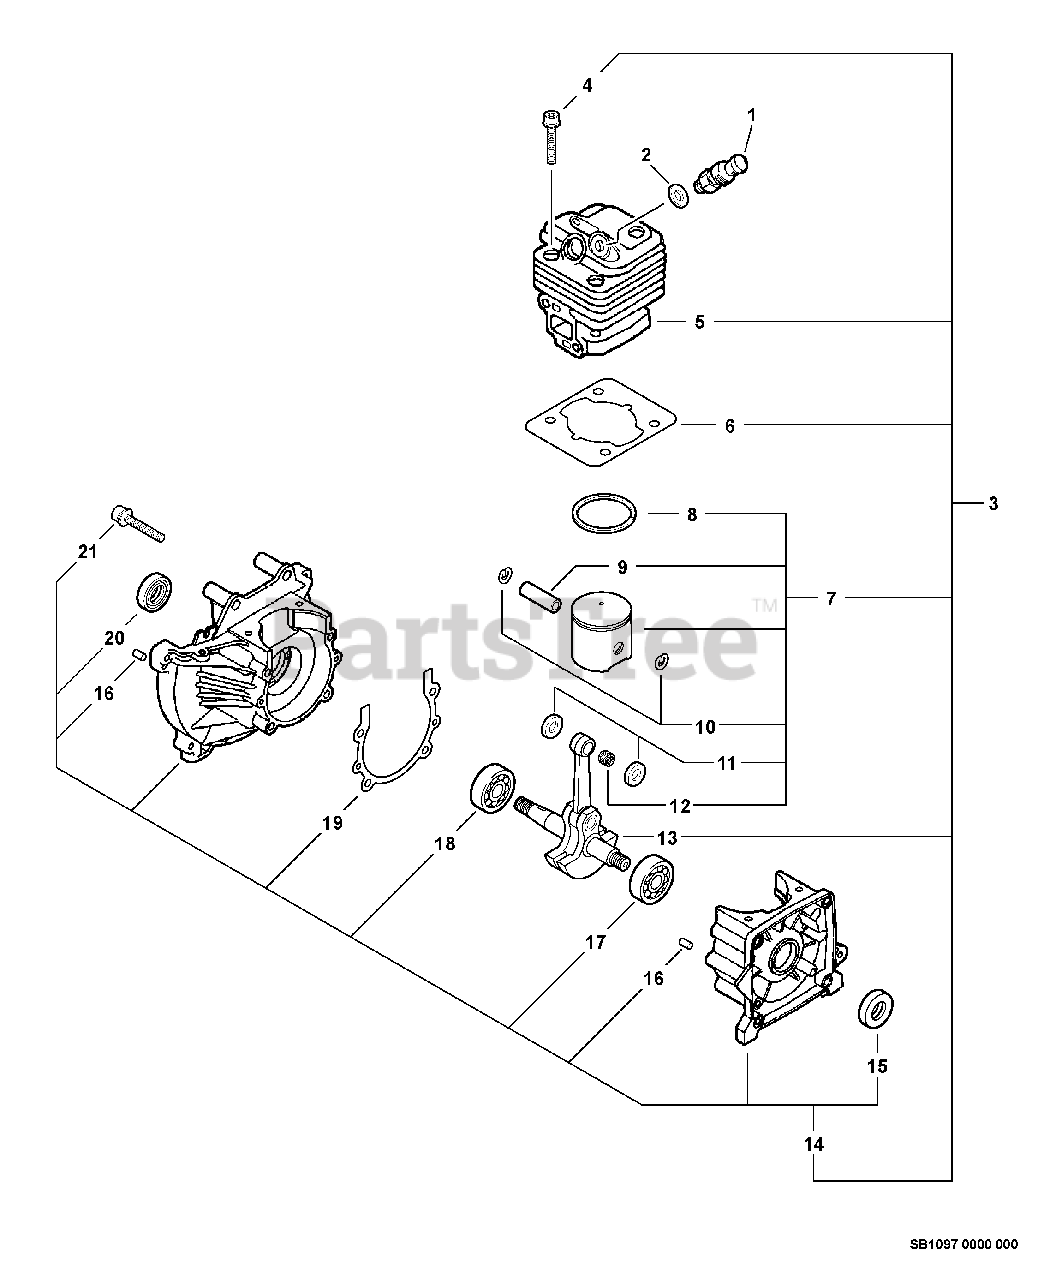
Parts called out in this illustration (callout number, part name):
1	DECOMPRESSION ASSY
2	WASHER
3	SHORT BLOCK -- SB1097
4	SCREW - 5X20
5	CYLINDER
6	GASKET, CYLINDER
7	PISTON KIT
8	RING, PISTON
9	PIN, PISTON
10	RING, RETAINING - 8
11	WASHER - 10
12	BEARING, NEEDLE
13	CRANKSHAFT ASSY
14	CRANKCASE KIT
15	SEAL, OIL
16	PIN - LOCATING
17	BEARING, BALL - 6201
18	BEARING, BALL - 6202
19	GASKET, CRANKCASE
20	SEAL, OIL
21	SCREW - 5X35
